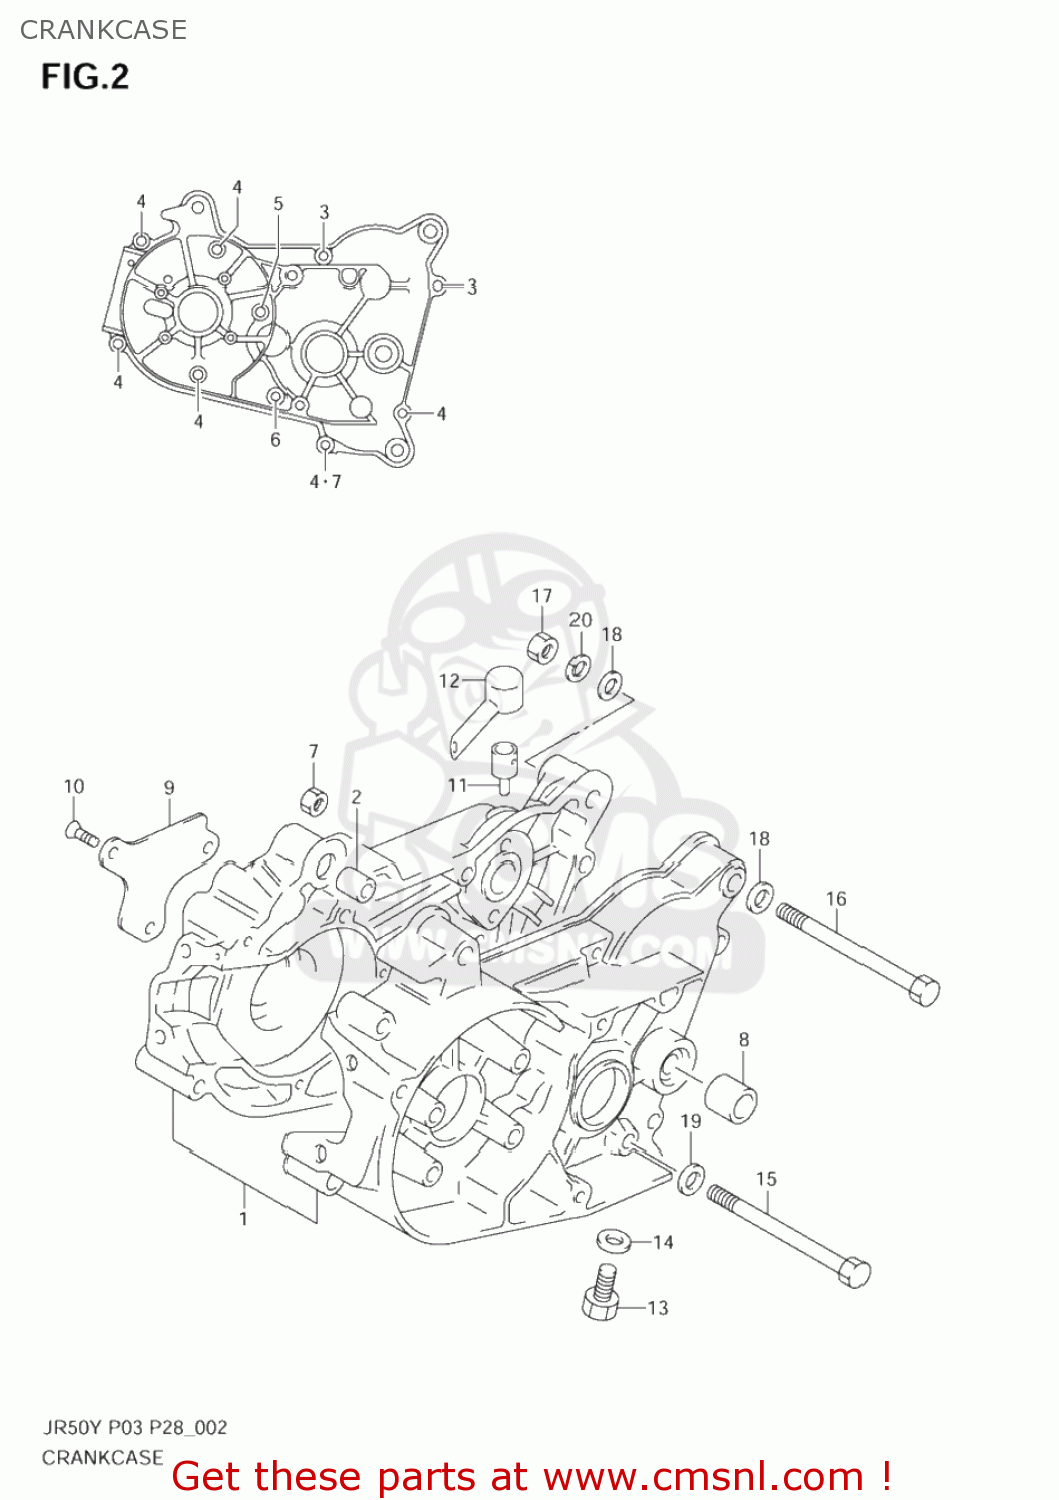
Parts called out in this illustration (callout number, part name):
1	CRANKCASE SET
2	PIN
3	SCREW 6X30
4	SCREW
5	SCREW
6	SCREW
7	NUT 6MM
8	BUSH
9	PLATE,OIL RESERVOIR
10	SCREW,UPPER
11	PLUG,T/M BREATHER
12	GASKET (NAS)
13	PLUG
14	GASKET(10X14X3.6) (NAS)
15	BOLT
16	BOLT
17	NUT
18	WASHER
19	WASHER(8.5X22X3.2)
20	LOCK WASHER
